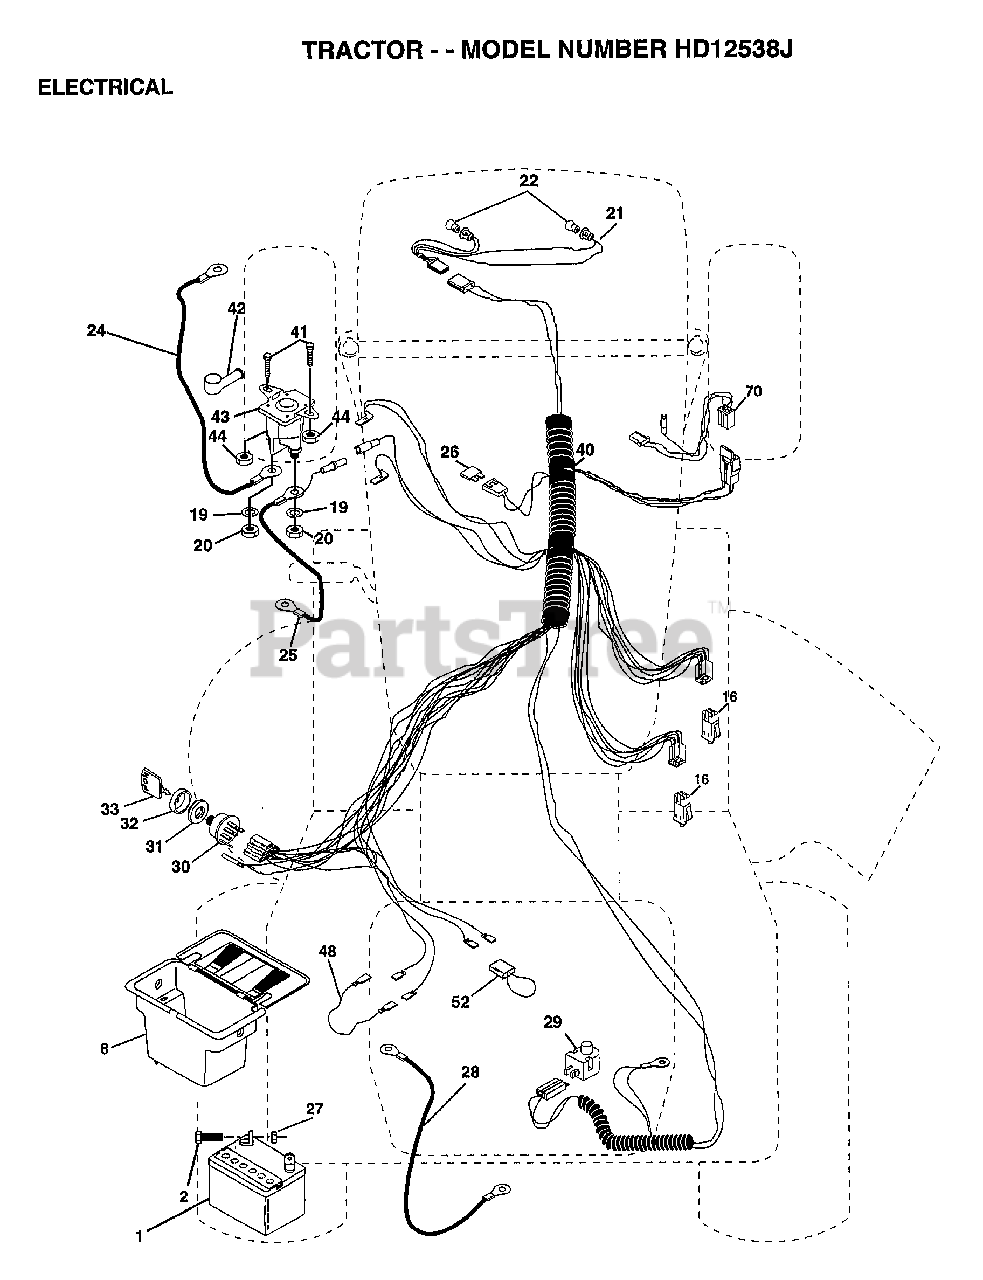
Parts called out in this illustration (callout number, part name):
2	BOLT LT
8	"CASE,BATTERY.MECH"
16	SWITCH INTERLOCK
20	NUT
21	HARNESS.ASM.LIGHT W/4152J
22	HEADLAMP BULB
24	"CABLE T, BATTERY"
25	CABLE.BTRY.6GA.RD
26	FUSE.15 AMP
27	NUT
28	CABLE T
29	SWITCH SEAT
30	SWITCH IGN 4POS
31	NUT IGNITION
32	COVER KEY SWITCH
33	KEY
40	HARNESS.IGNITION
41	BOLT HXHD FIN
44	NUT HXKEP 1/4X20
48	ADAPTER AMMETER
52	PROTECTION LOOP
70	HARNESS.ENGINE
